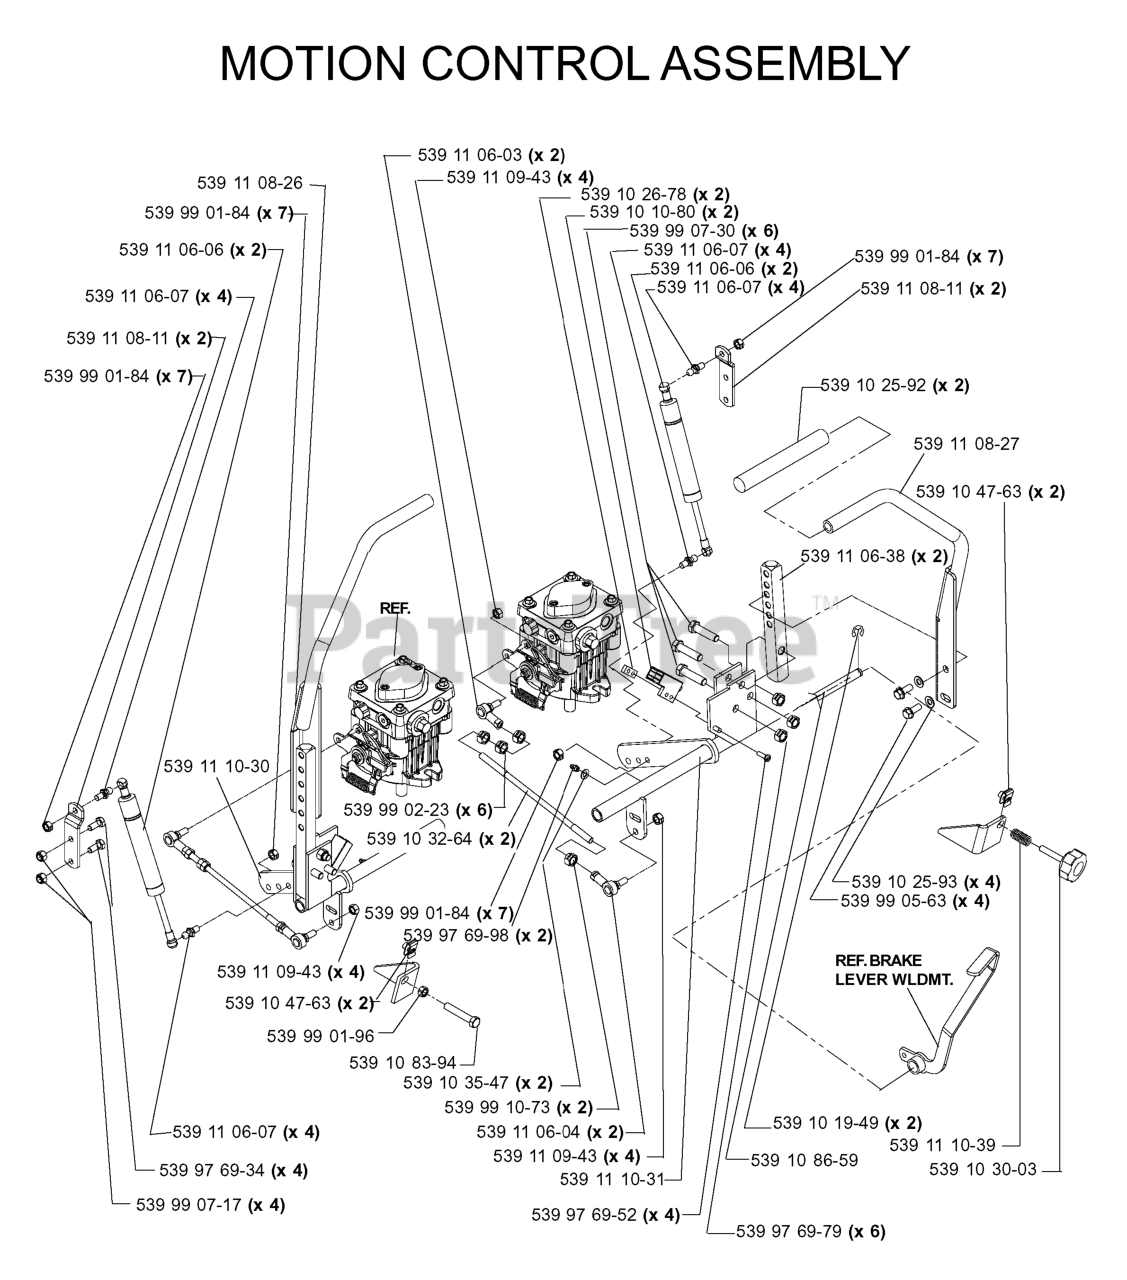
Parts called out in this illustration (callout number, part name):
1	HOUSING
6	ARM.SUSPENSION.MOWER.R
7	SCREW.#10 X 0.750.BOS
8	BOLT.WASHER.ASM.7/16-2
11	BLADE 38" PREMIUM
13	SHAFT.ASM.MDRL.N/GREASE.38
14	RP.HOUSING.MANDREL.4PT.
19	BOLT.SHOULDER
21	LOCKNUT
23	BRKT.DEFLECTOR.38"2005+
24	CAP-SLEEVE LT
25	SPRING.TORSION.DEFLECT
26	NUT PUSH M
27	SHIELD.DEFLECTOR.MWR.38-7/97CM
29	ROD.HINGE
30	SCREW, WASHER HEAD
31	WASHER.SPACER.MANDREL
32	PULLEY.MANDREL.5.0.PD.38"
33	NUT.FLANGE.LOCK.TOP
34	BOLT.3/8-16X1.50
37	WASHER
38	KEEPER BELT LH MANDREL
40	NUT LOCK FLG 3/8-16 UNC
42	SPRING.TORSION.BRAKE
43	SRPING.TORSION.RETAINE
46	SCREW.1/4-20X5/8
56	SPACER.RETAINER
57	SCREW 3/8-16X1
59	GUARD, BELT
60	ARM BRAKE MOWER RH 38"
63	RP ARM.BRAKE.MOWER.38"LH.TEX
64	LINK BRAKE
67	HANDLE.CLUTCH.CABLE.LT
69	BOLT
70	CLUTCH.ASM.MANUAL.LT.PRED
122	KEEPER BELT ENGINE LH
123	KEEPER BELT RH
144	KEEPER BELT
145	PULLEY.IDLER.48"PRIMARY
147	SPRING RETURN
152	CABLE.CLUTCH.MANUAL.
188	STUD.FASTNER.W/ANTI-ROTATE
189	NUT LOCK HEX FLANGE 5/16-18
195	SCREW, 3/8-16X3/4
199	BAFFLE.VORTEX.FRONT.38"
208	SCREW 3/8-16X1/2
209	WASHER 12/32X2X10GA
